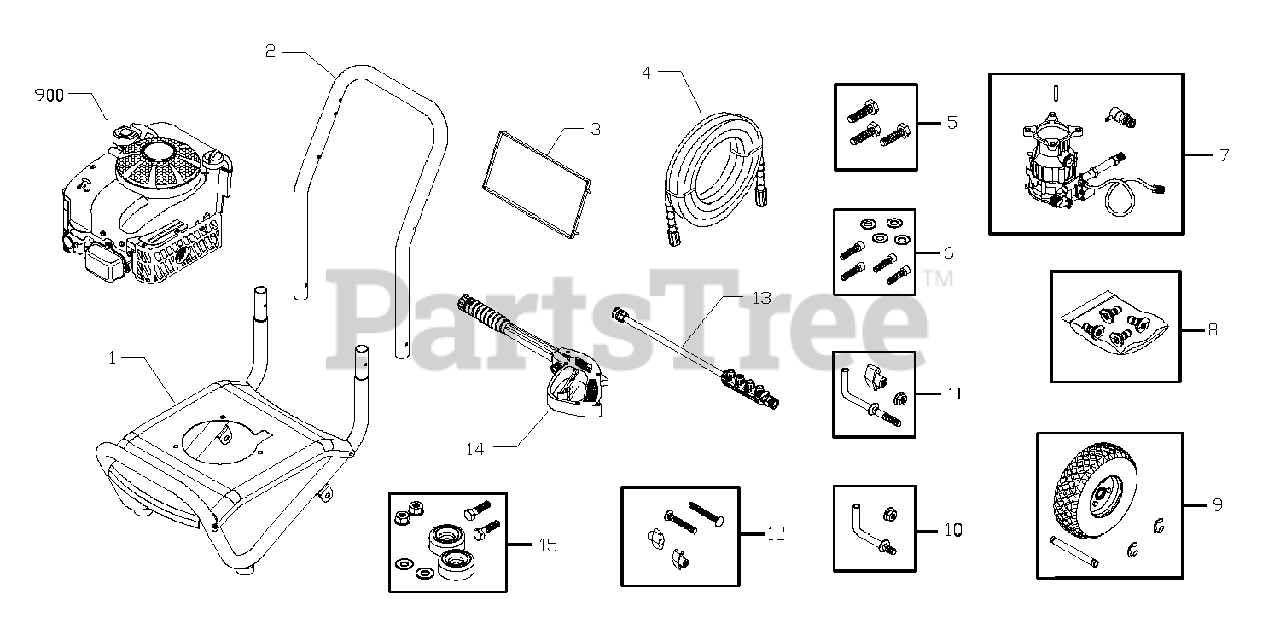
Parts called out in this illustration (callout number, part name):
1	ASSY, Base
3	ASSY, Billboard/Decals
4	HOSE
5	KIT, Engine Mounting Hardware
6	KIT, Pump Mounting Hardware
7	ASSY, Pump (see page 3)
8	KIT, Spray Tips, QC
9	KIT, Wheel
10	KIT, Hook, Base
11	KIT, Hook Handle
12	KIT, Handle Connector
13	ASSY, Extension w/Nozzle Holder
14	GUN
15	KIT, Vibration Mount
